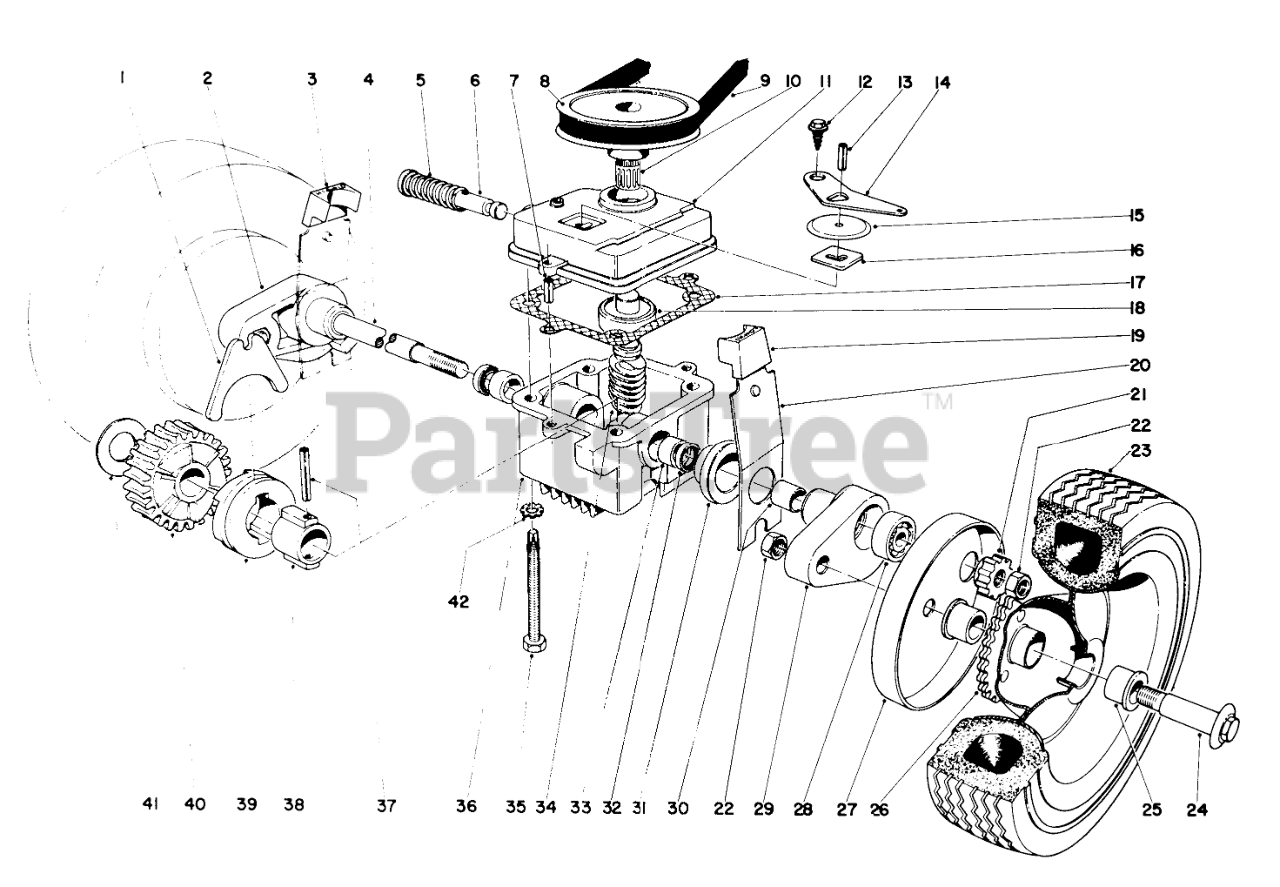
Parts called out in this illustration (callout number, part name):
1	SHIFTER FORK
2	Pivot Arm (Incl. Ref. 30)
4	DRIVE SHAFT
5	SPRING
6	Shift Rod
7	3/16 X 1/2 ROLL PIN
8	PULLEY
9	V BELT
10	Tolerance Ring
11	GEAR CASE COVER
12	Screw
13	PIN-ROLL
14	SHIFTER ARM
15	TRANS DUST COVER
16	LATCH PLATE
17	GASKET
18	Bearing
19	ARM KNOB
20	Spring Arm
21	PINION GEAR
22	Nut
23	8 TIRE
24	Wheel Bolt
25	FLANGE BUSHING
26	Wheel (Incl. Ref. No. 25)
27	WHEEL COVER
28	.375 RPP BALL BEARING
29	Pivot Arm (Incl . Ref . 30)
30	BUSHING
31	End Cap
32	Seal
33	Bushing
34	Worm Shaft
35	Screw
36	Gear Case (Incl. Ref. No.33)
37	PIN-SPRING
38	SLEEVE
39	Clutch
40	Worm Gear
41	THRUST WASHER
42	WASHER-LOCK/EXT
